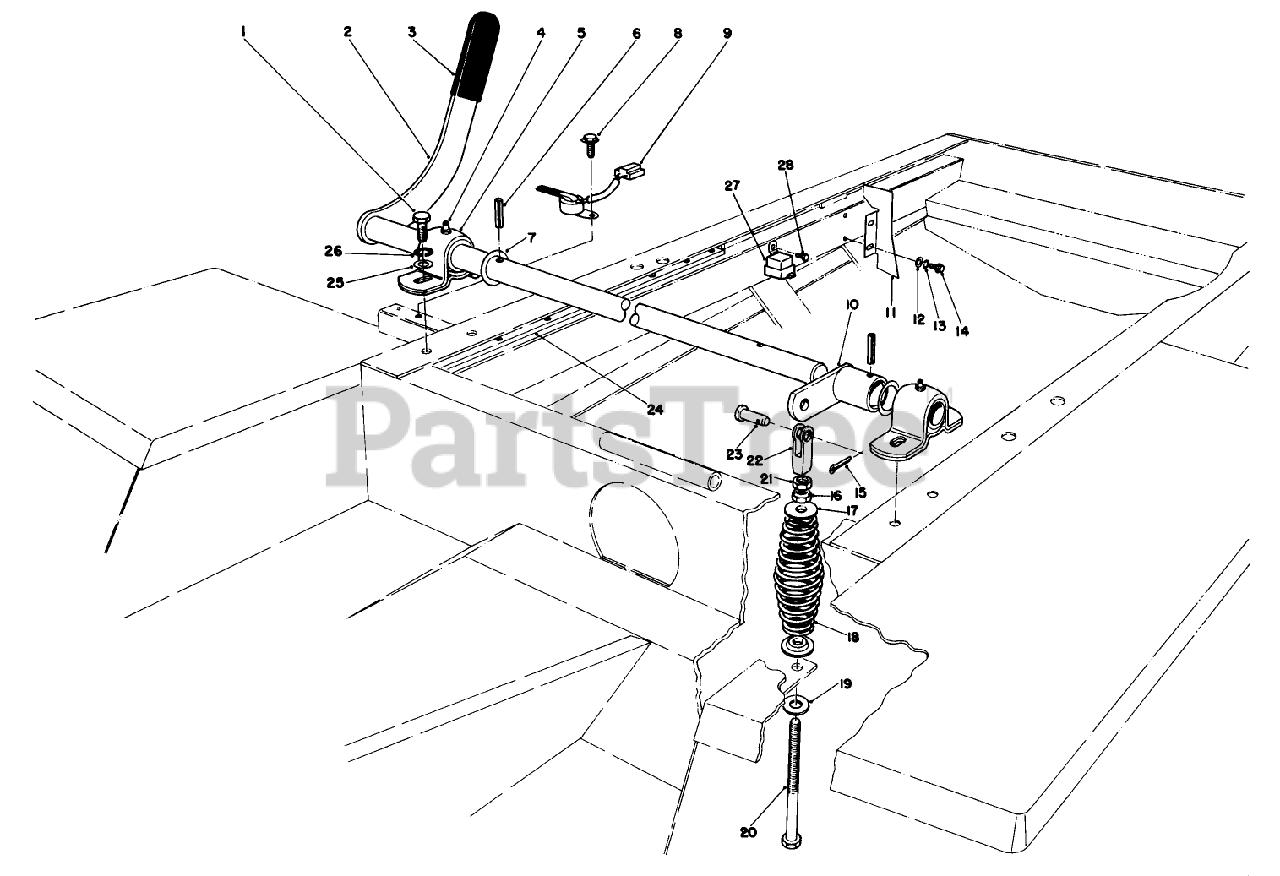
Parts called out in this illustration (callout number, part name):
1	SCREW-HH
2	P.T.0. Lever
3	GRIP-HANDLE
4	FITTING-GREASE
5	BEARING
6	PIN-SPRING
7	THRUST WASHER
8	SCREW-THD FRM,HWH
9	SWITCH ARM
10	Arm-Engagement
11	Shield-Heat
12	WASHER-PLAIN
13	WASHER-LOCK
14	SCREW-HWHTF
15	PIN-COTTER
16	NUT-HEX
17	SPRING RET TOP
18	COMP SPRING
19	WASHER
20	SCREW-ADJUSTING
21	NUT-HJ
22	PLUG-PIPE, SQH
23	PIN-CLEVIS
24	Bar Frame Rail
25	WASHER-FLAT
26	WASHER-LOCK
27	RELAY
28	SCREW-HWH
